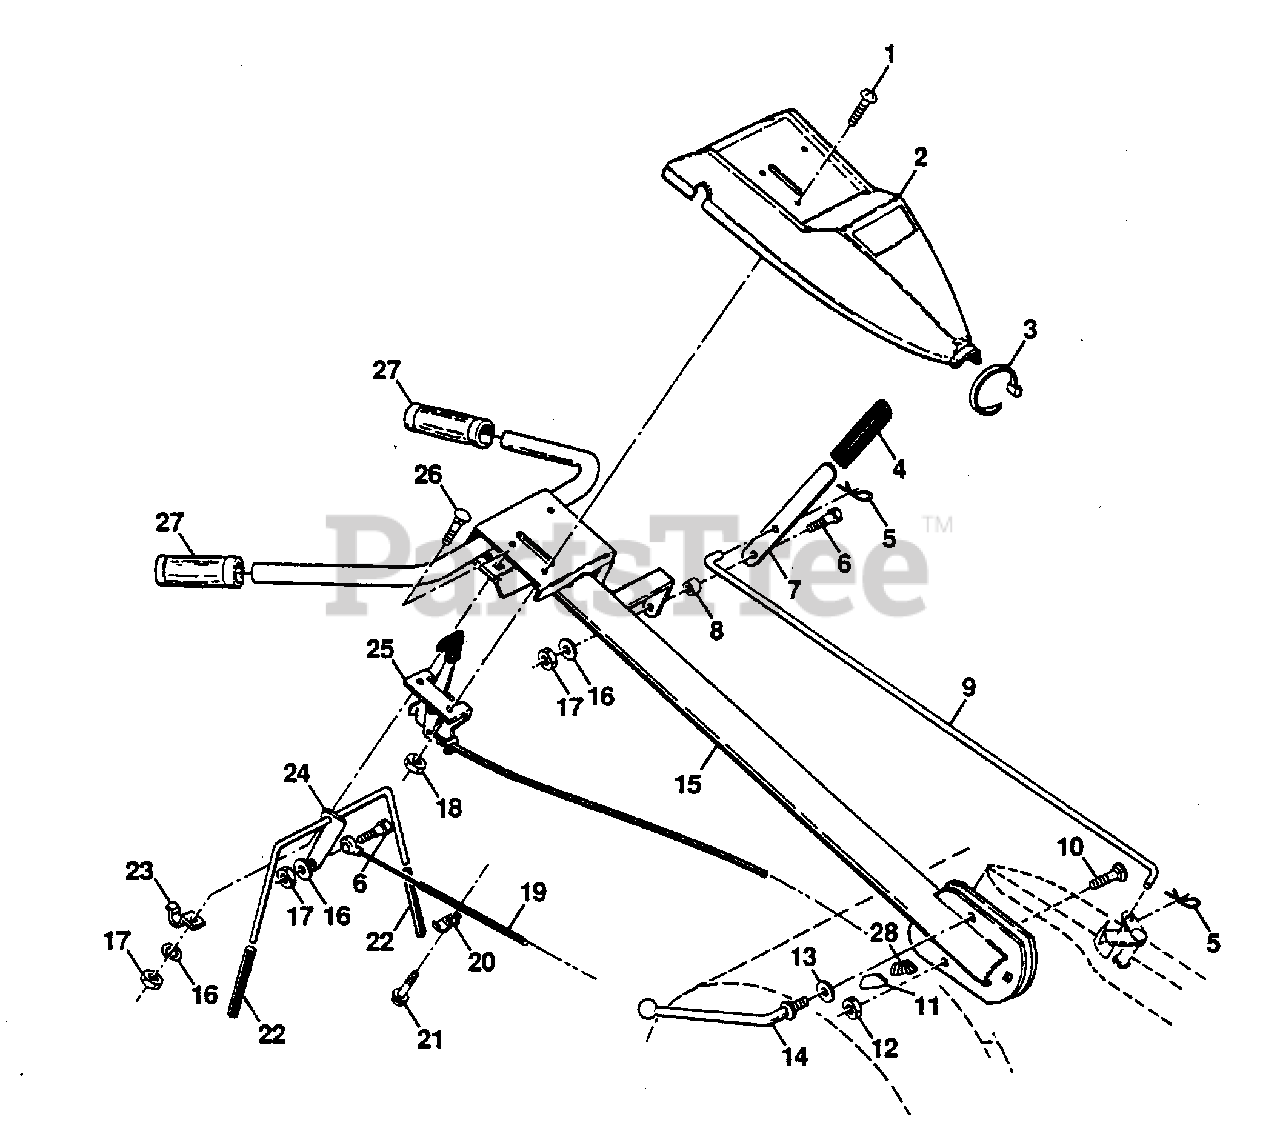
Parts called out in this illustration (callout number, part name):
1	Screw, Pan Hd. #10-24 UNC
2	Panel, Control
4	Grip, Handle
5	Clip, Hairpin
6	Bolt, Shoulder
7	Handle, Shift
8	Grommet, Rubber
9	Rod, Shift
10	Bolt, Carriage 3/8-16 x 1
12	Nut, Centerlock 3/8-16
13	Washer 13/32 x 1 x 11 Ga.
14	Lever, Lock, Handle
15	Handle
16	Washer, Lock 1/4
17	Nut, Hex 1/4-20
18	Nut, Keps #10-24 UNC
19	Cable, Clutch
21	Screw, Hex Washer Hd. Slotted #10-24 x 1/2
22	Grip, Bar, Control
23	Clamp, Bar, Control
24	Bar Assembly, Control
25	Control, Throttle
26	Bolt, Carriage 1/4-20 UNC x 1/2
